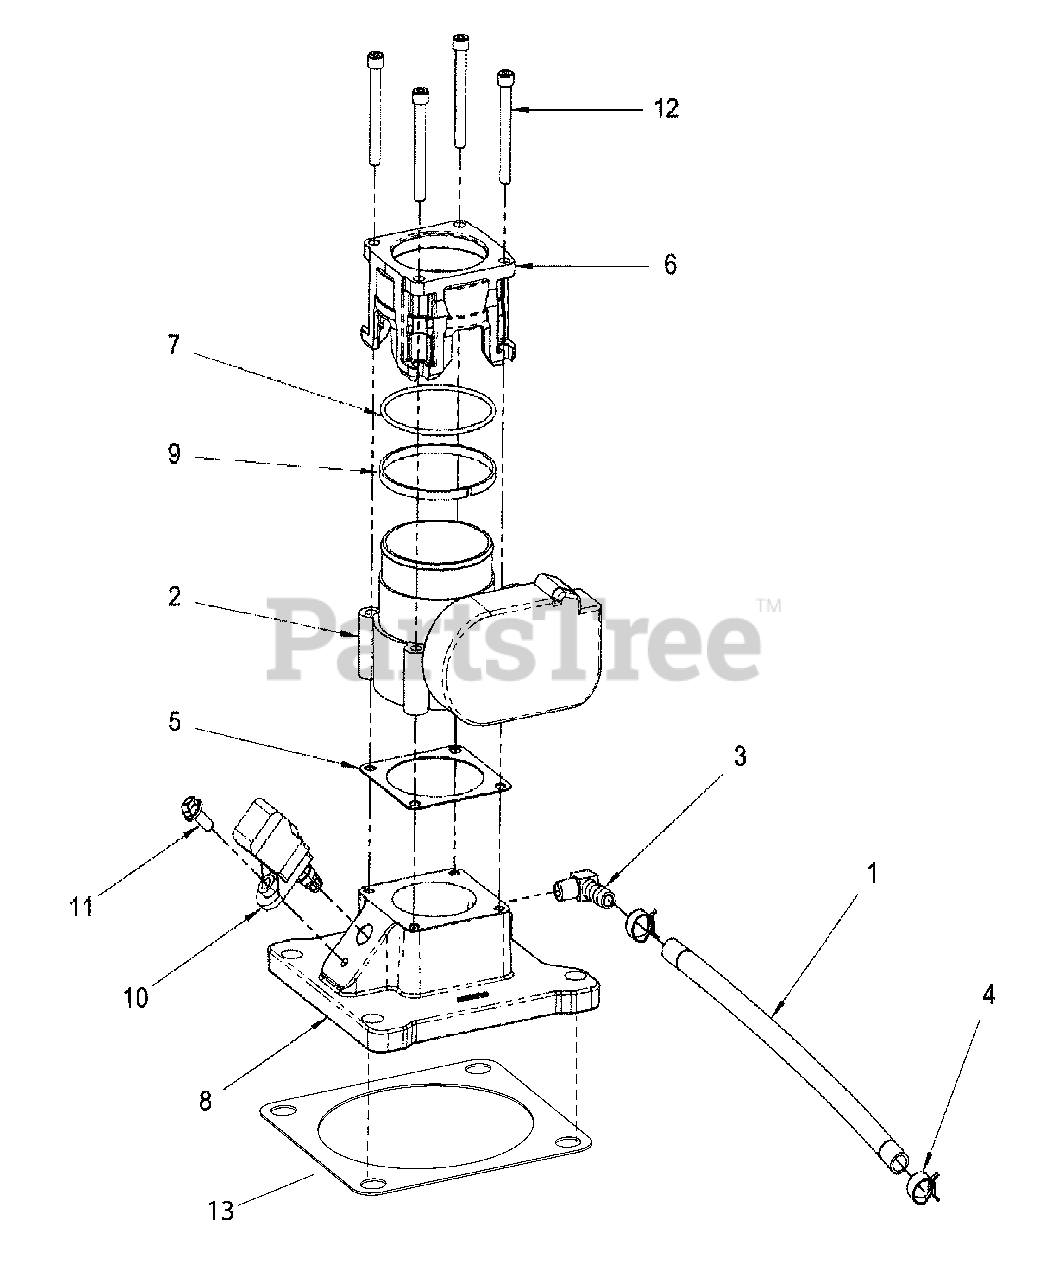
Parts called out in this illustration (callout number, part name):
1	FUEL HOSE
3	* FITTING
4	* CLAMP
6	ADAPTER
8	* ADAPTER
11	* BOLT
12	* BOLT
